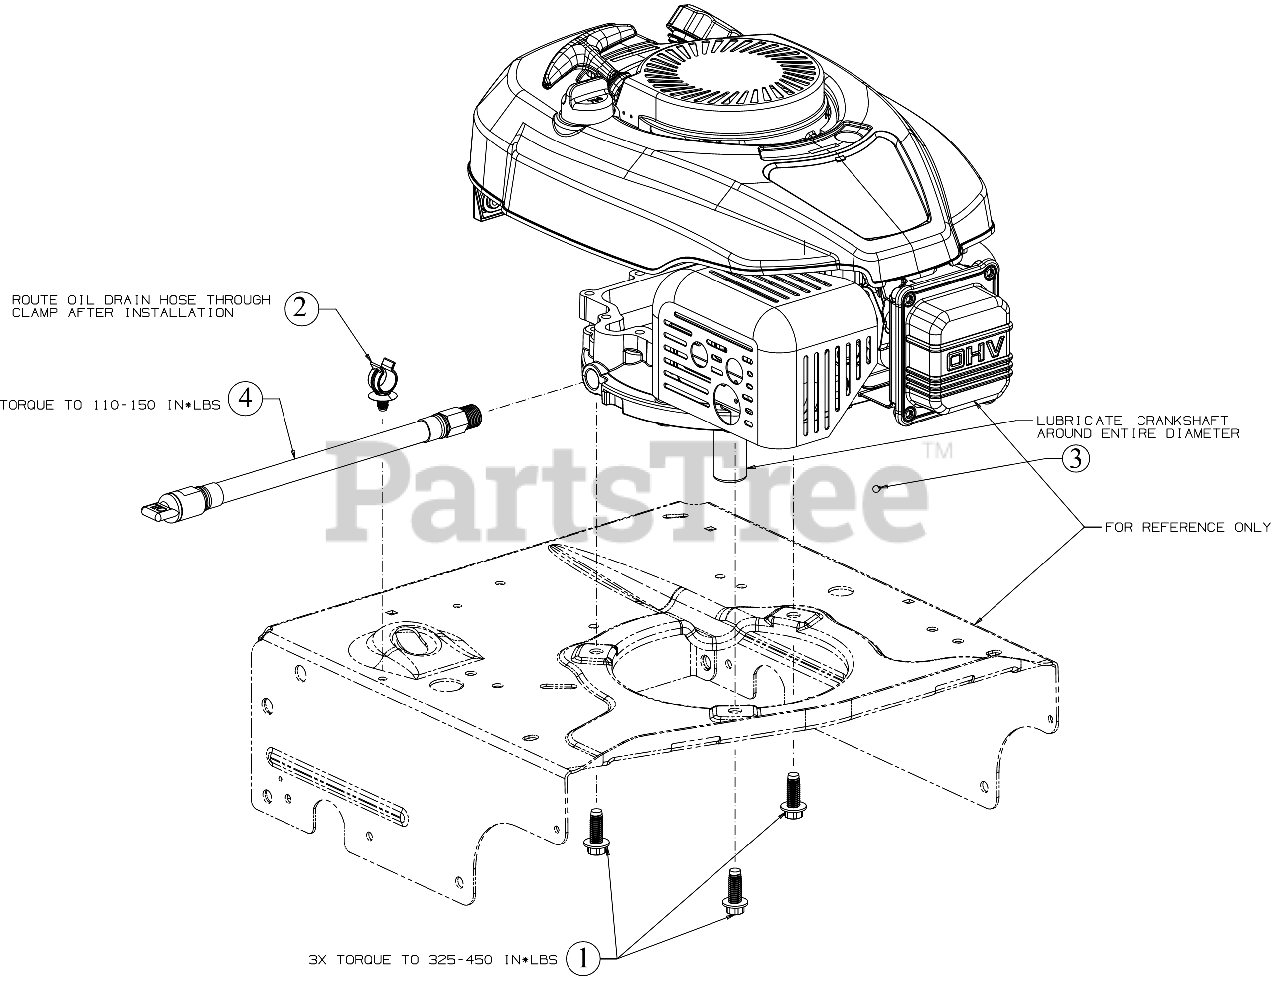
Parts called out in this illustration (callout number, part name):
1	SCREW 3/8-16 x 1
2	DRAIN HOSE CLIP
3	GREASE
4	OIL DRAIN HOSE
